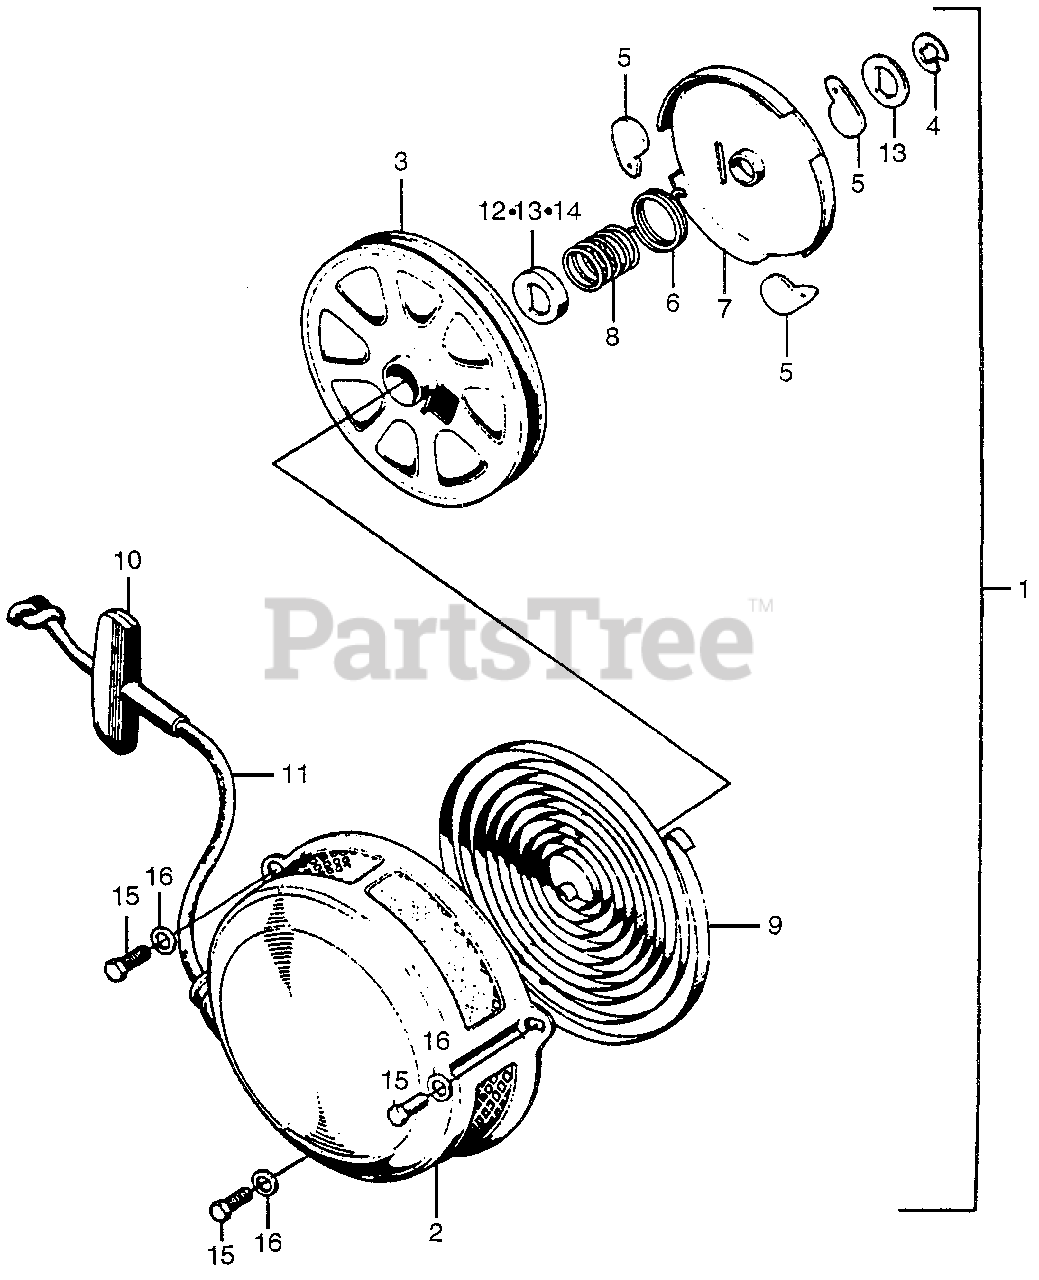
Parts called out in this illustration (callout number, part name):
1	RECOIL, STARTER *R8* (BRIGHT RED) (NOT AVAILABLE)
2	CASE, RECOIL STARTER *R8* (BRIGHT RED) (NOT AVAILABLE)
3	PULLEY, RECOIL STARTER
5	RATCHET, STARTER
6	SPRING SET
7	PLATE, FRICTION
8	SPRING, FRICTION
9	SPRING, STARTER RETURN
10	KNOB SET, STARTER
11	ROPE, RECOIL STARTER (#6X54")
13	WASHER B (NOT AVAILABLE)
13	WASHER B
14	WASHER C
15	BOLT, HEX. (6X12)
16	WASHER, PLAIN (6MM)
